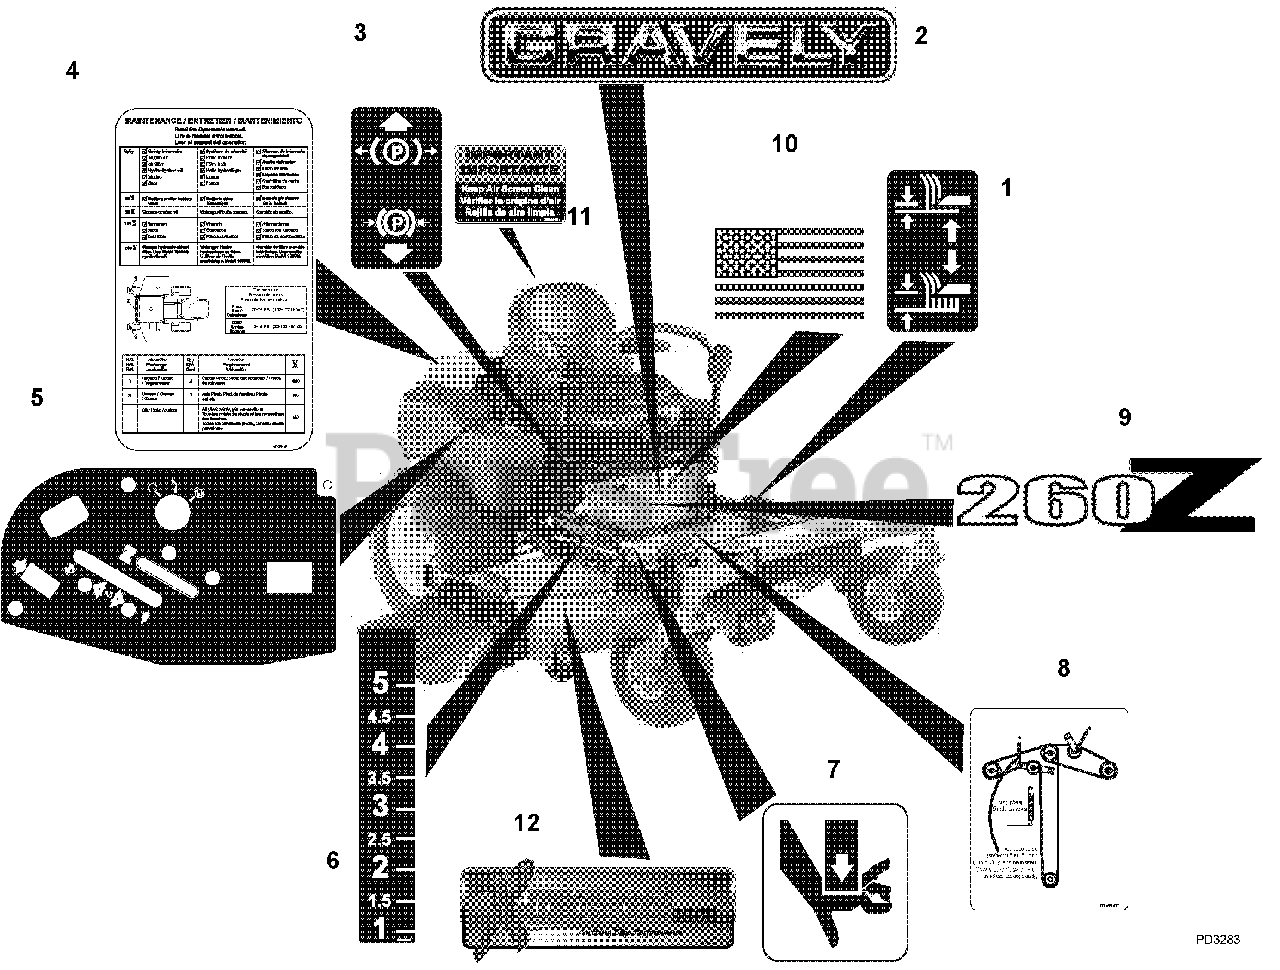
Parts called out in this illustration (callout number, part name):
1	Decal, Lift Lever (992149, 150, 153, 154, 157, 159)
2	Decal, 15 in. Gravely Logo
3	Decal, Parking Brake Lever
4	Decal, Maintenance Instructions
5	Decal, Control Panel (992146, 147, 148, 149, 149, 150, 151, 153, 154, 155)
6	Decal, Height of Cut (992149, 150, 153, 154, 157, 159)
7	Decal, Pinch Point (992149, 150, 153, 154, 157)
8	Decal, Belt Diagram
9	Decal, PM-260Z (992147, 151, 152, 153, 154, 155, 159)
10	Decal, American Flag
11	Decal, Warning Clean Debris (992152, 157, 159)
12	Decal, X-Factor Deck
